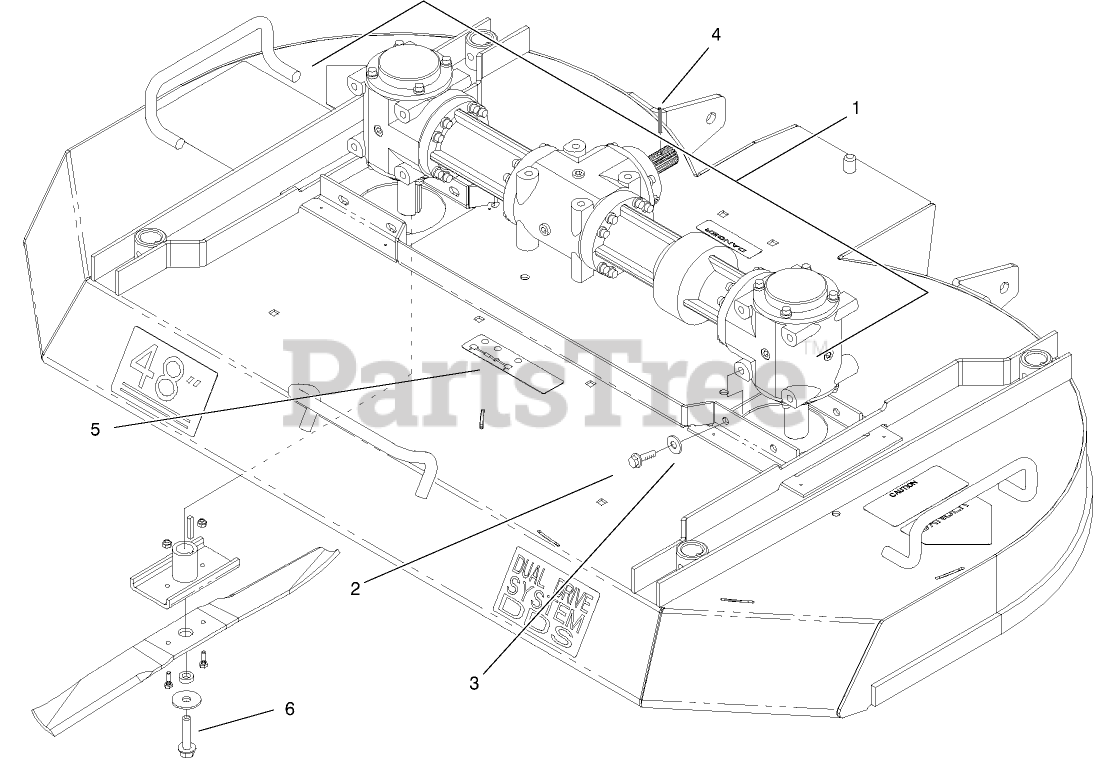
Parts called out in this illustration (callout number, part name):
1	Gearbox ASM
2	SCREW-HSH
3	WASHER
4	PIN-SPRING
5	DECAL-TRANSMISSION FLUID
6	BOLT-BLADE, LH THREAD
